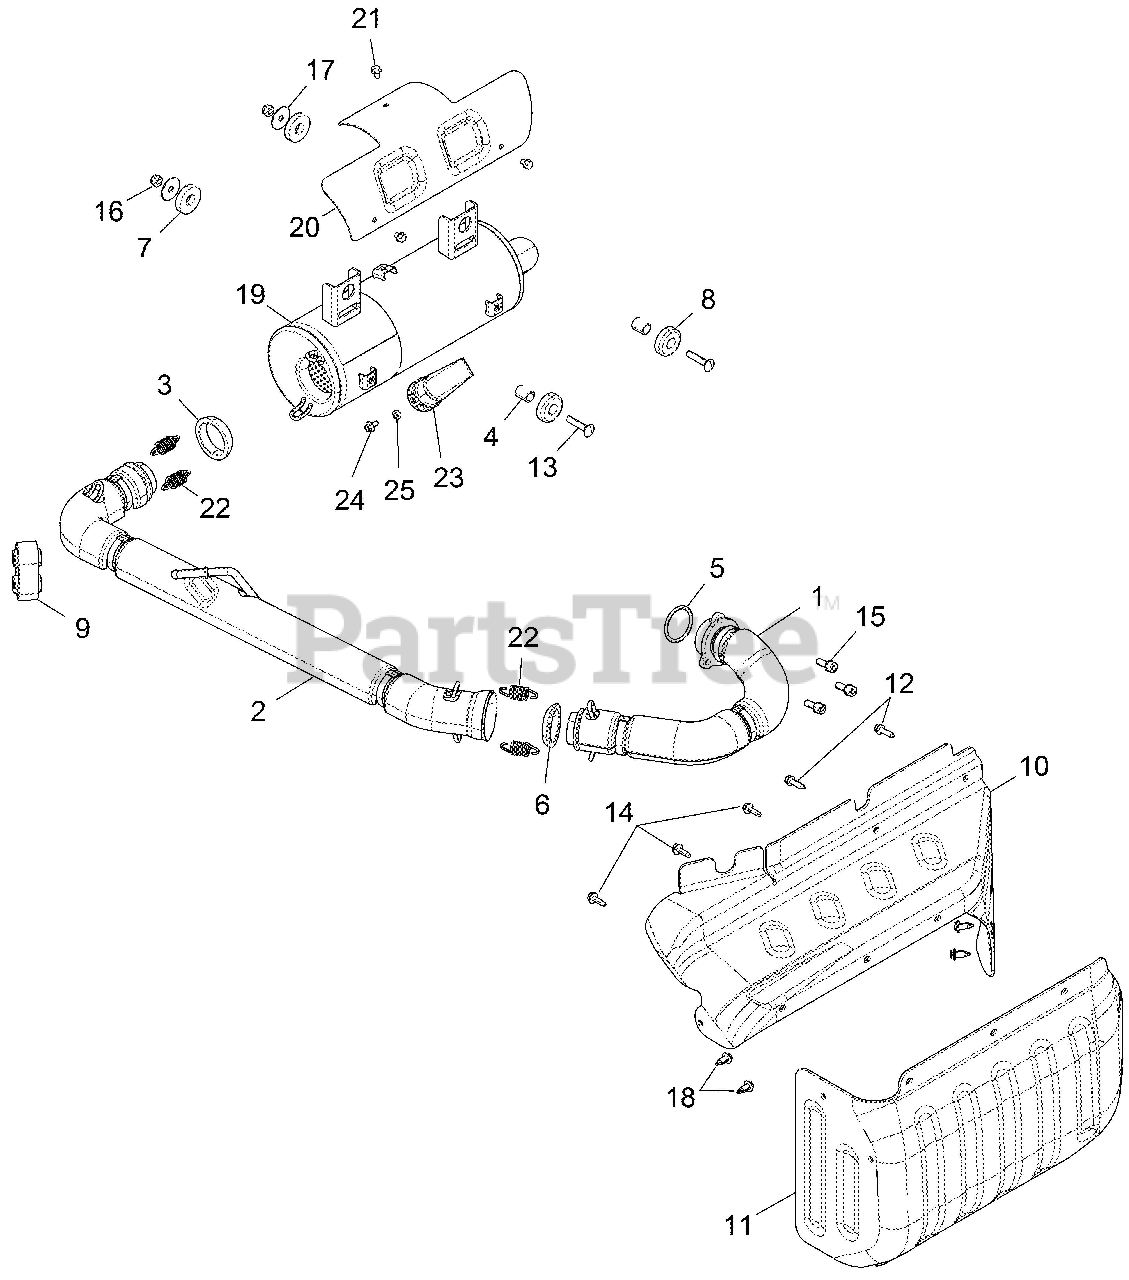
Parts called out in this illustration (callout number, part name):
1	ASM., HEADPIPE, FRONT
2	ASM., HEADPIPE
3	SEAL-EXHAUST, SOCKET
5	GASKET-EXHAUST SEALING
6	SEAL-EXHAUST
7	WASHER, SILENCER MOUNT
8	DAMPER-VIBRATION
9	MOUNT-ISOLATOR
10	SHIELD-HEAT,FOIL,TOP
11	SHIELD-HEAT,FOIL,BOTTOM
12	SCREW (10)
13	SCR-CAR M8X1.25 40 8.8 ZOD
14	SCR-M6X1.0X20,HXHD,FLG,TDFM,BL
15	SCR-M8X1.25X22,HX/SO
16	NUT-M8X1.25,FLG,NYLOC-OLIVE D
18	RIVET-TUFLOK,.315-.325X.787 (5
19	ASM., SILENCER
20	SHIELD-SILENCER
21	SCREW(10)
23	ARRESTOR, SPARK
24	SCREW,HXFLGHD,M6X12
